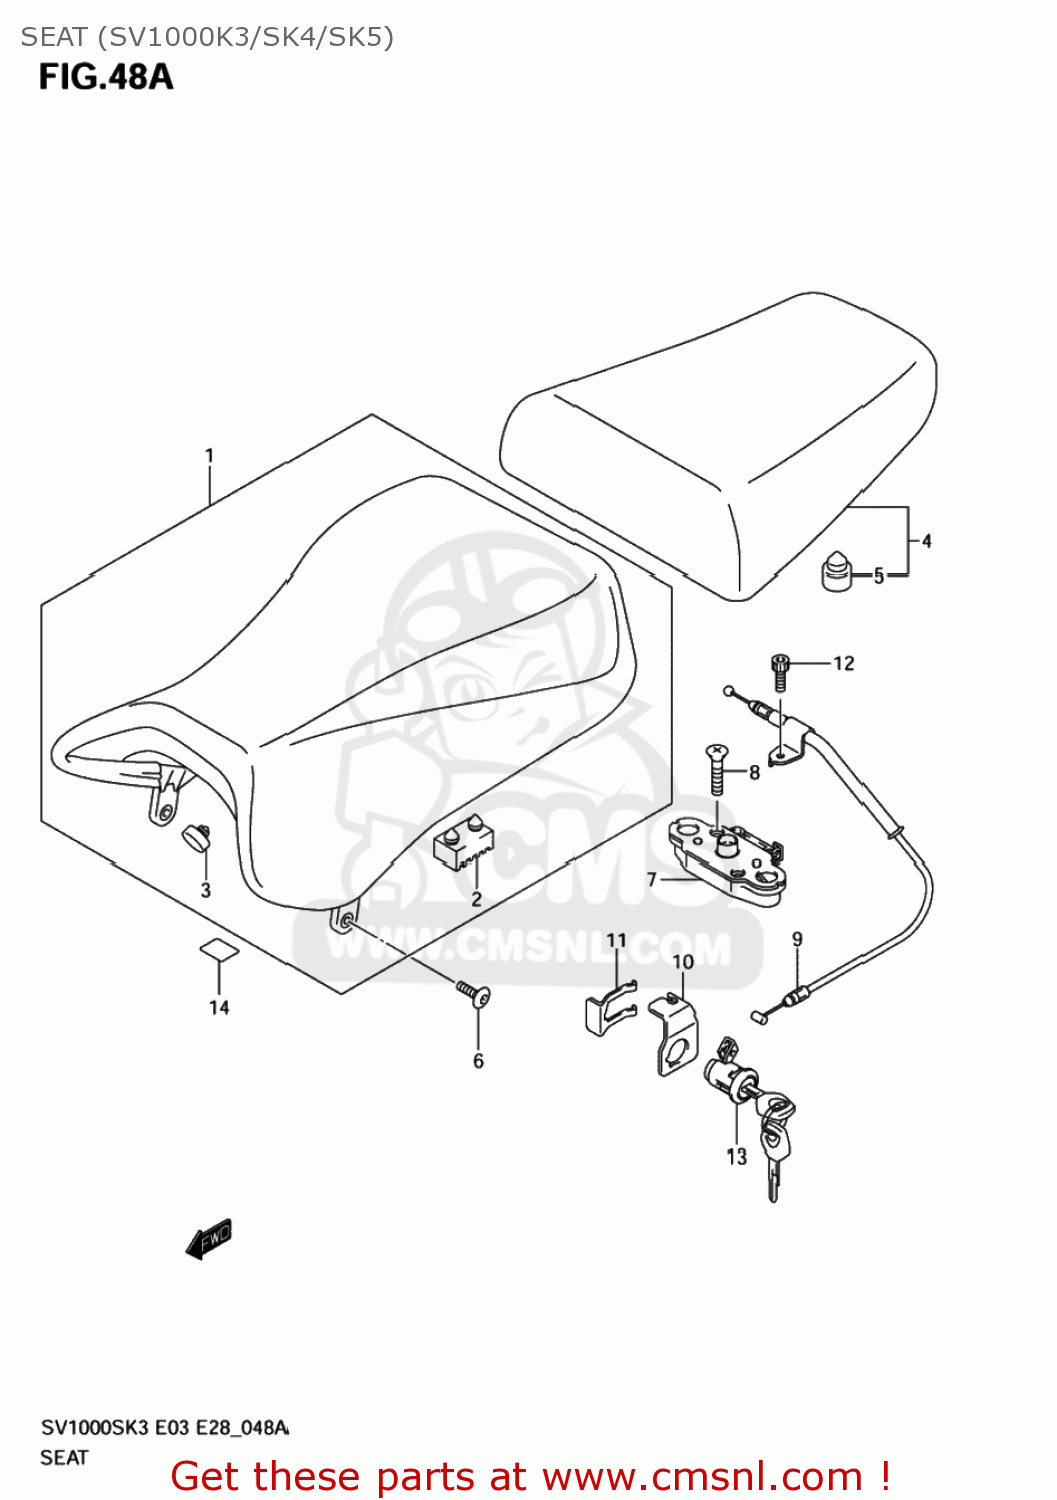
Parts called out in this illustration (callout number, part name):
1	SEAT ASSY
2	CUSHION
3	CUSHION,FR
4	SEAT ASSY,PILLION
5	CUSHION
6	BOLT(6X18)
7	BRACKET,SEAT SUPPORT,RIGHT
8	SCREW
9	CABLE,SEAT LOCK
10	GUIDE,SEAT LOCK CABLE
11	PLATE,SEAT LOCK ASSY
12	BOLT,OIL FILLE
13	LOCK SET,SEAT
14	TAPE,FUEL TANK
